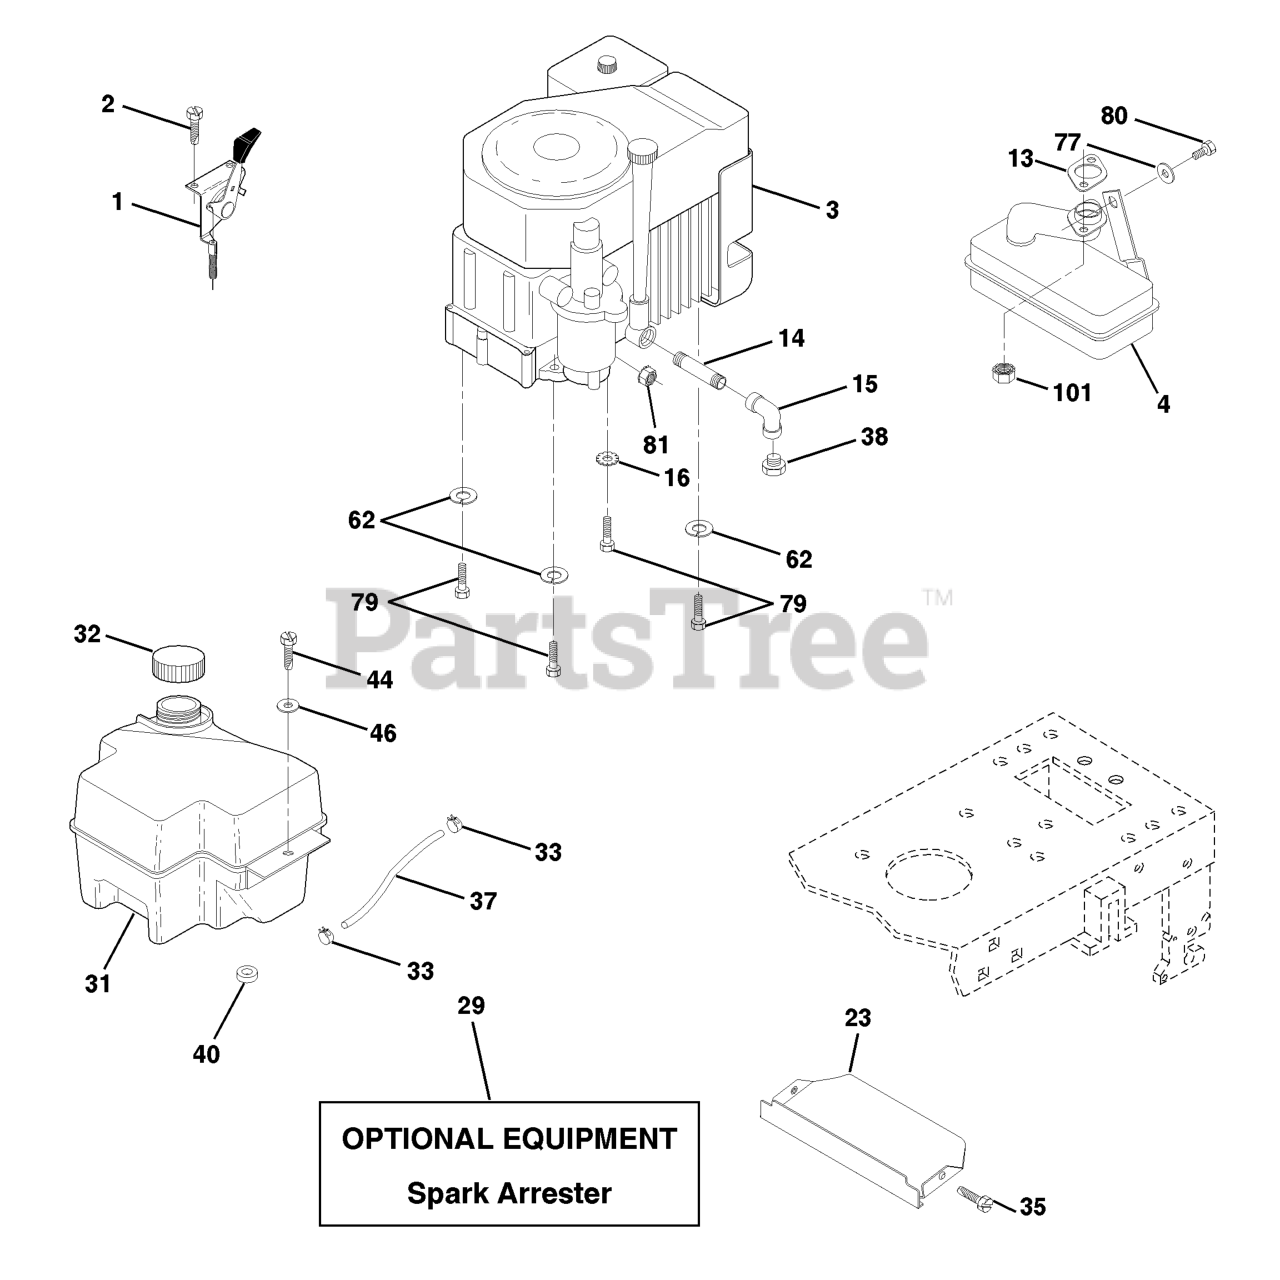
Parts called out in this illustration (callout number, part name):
1	CONTROL SWITCH 27 LH
2	SCREW LT
4	MUFFLER.KOHL.CV.SINGLE.W/PORT
13	KOHLER GASKET
14	Nipple Pipe 3/8 Npt X 3-1/2
15	ELBOW
16	WASHER EXT TOOTH LOCK 5/16
29	KIT.SPARK ARRESTOR 794945 B&S
31	FUEL TANK
32	FUEL CAP
33	HOSE CLAMP
35	SCREW.THDROL.5/16-18X3/4.TTY
37	LINE.FUEL.20
38	Plug Oil Drain
40	BUSHING.SNAP.NYL.BLK.
44	SCREW HEX CRT
46	WASHER
62	WASHER.LOCK.HVY.HLCL.SPR.5/16
77	WASHER
79	BOLT, HEX
80	Bolt Hex Hd 5/16-18 UNC x 1/2
81	NUT FLANGE 1/4-20 STARTER NUT
101	FLANGE NUT
